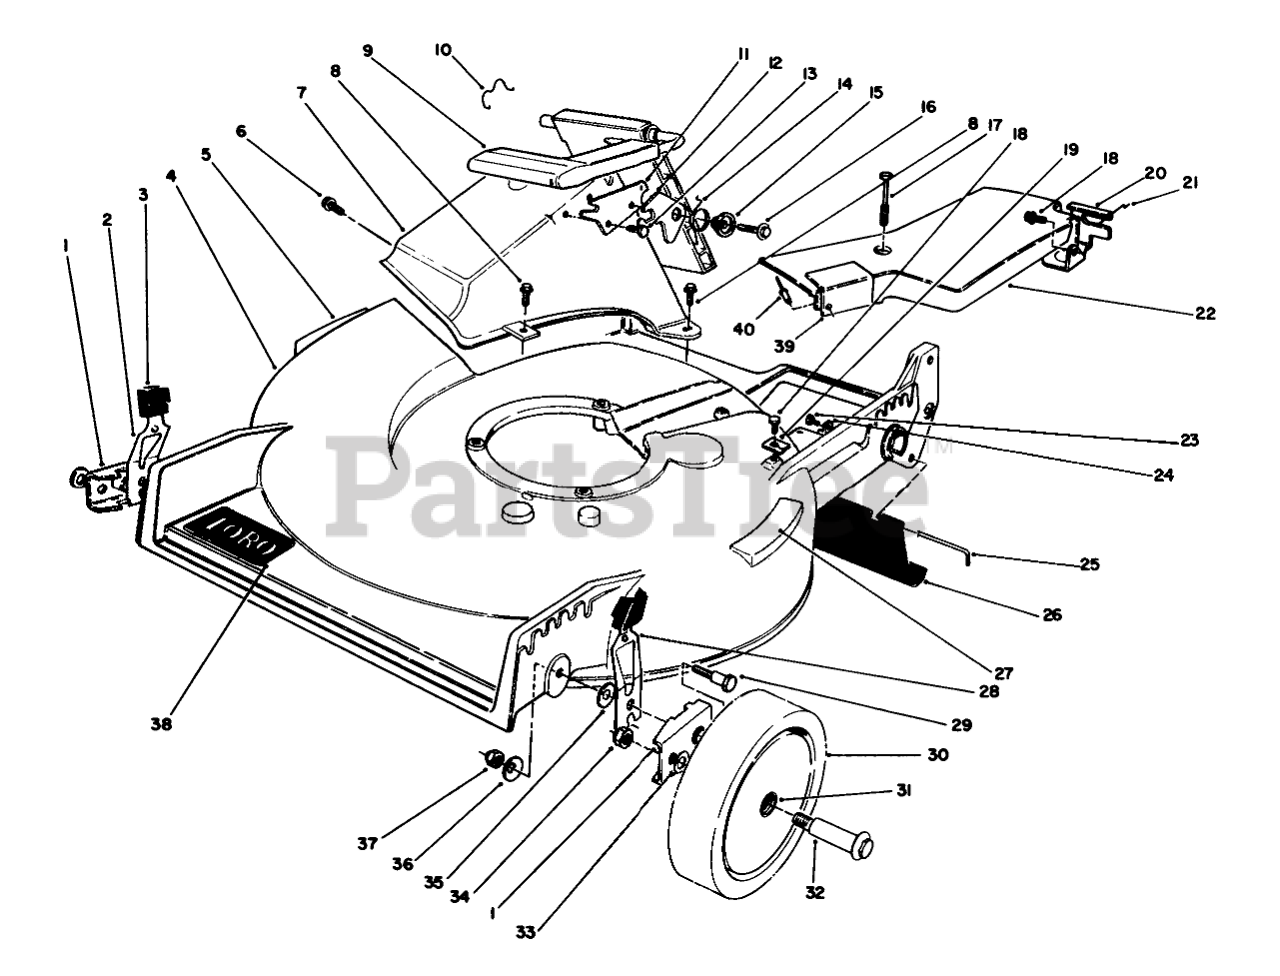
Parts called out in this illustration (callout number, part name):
1	HP PIVOT ARM ASM
2	L. HP SPRING ARM ASM
3	KNOB-ARM
4	Housing (Incl. Ref. #5, 27 & 38)
5	DECAL-DANGER
6	SCREW AND WASHER ASM
7	Tunnel Discharge
8	SCREW-HWH
9	Discharge Door Assembly
10	DOOR RET SPRING
11	DOOR LATCH PLATE
12	SAFETY LATCH
13	SCREW-PLASTITE
14	TORSION SPRING
15	DOOR SPACER
16	SCREW-HWH
17	SCREW-HHFTF
18	SCREW-HWHTF
19	CLAMP-CABLE
20	Bracket-Traction Adj.
21	RETAINER-CABLE
22	BELT COVER ASM
23	SCREW
24	CLAMP-CABLE
25	ROD-SHIELD
26	SHIELD-TRAILING
27	STEP PAD DECAL
28	R HP SPRING ARM ASM
29	PIVOT SCREW
30	Wheel & Tire Assembly (Incl. Ref. #31)
31	BUSHING
32	BOLT-WHEEL
33	WASHER
34	Nut
35	WASHER-PIVOT
36	WASHER-BELLEVILLE
37	NUT-LOCK, NI
38	DECAL
39	HEAT SHIELD
40	RIVET-HEAD, FLAT
